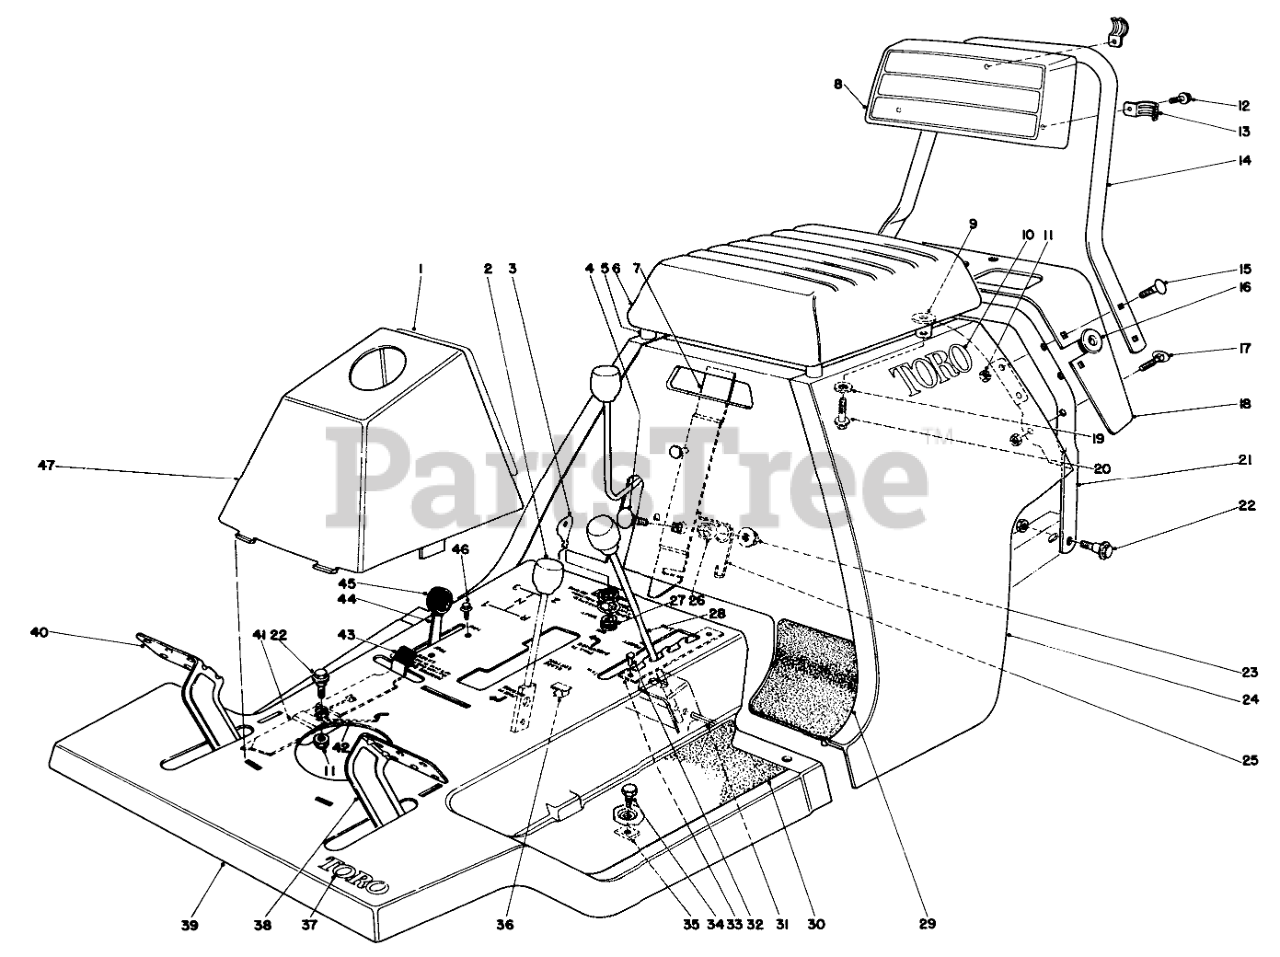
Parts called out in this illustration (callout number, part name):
1	Decal Tower
3	Key
4	BOLT-CARR
5	Spacer
7	Handle Latch
8	Backrest
9	WASHER-FLAT
10	TORO LOGO DECAL
11	NUT-LOCK, CONE
12	SCREW-HHF
13	CLAMP-CONDUIT
14	Handle Upper
15	SCREW-CARR
16	Starting Ferrel
17	HANDLE SCREW
18	Extension Rear Body
19	WASHER-FLAT
20	HEX FLANGE SCREW
21	Handle Lower
22	SCREW-SHOULDER
23	NUT-HF
24	Rear Body
25	Latch Return Spring
26	Spacer
27	ON-OFF SWITCH 21-8-468
28	Height of Cut Lever
29	Heel Pad-LH.
30	Foot Tread LH.
31	Spring Pin
33	Height Adjustment Plate
34	SCREW-HH
35	NUT-TINNERMAN
36	Wire & Cable Tie
37	DECAL
38	Clutch Pedal
39	Front Body (Incl. Ref. #32 & 33)
40	Brake Pedal
41	Parking Brake
42	SPRING-PARKING BRAKE
43	TIP-PARKING BRAKE
44	Throttle Control
46	8X1/2 SELF TAP SCREW
47	Tower
